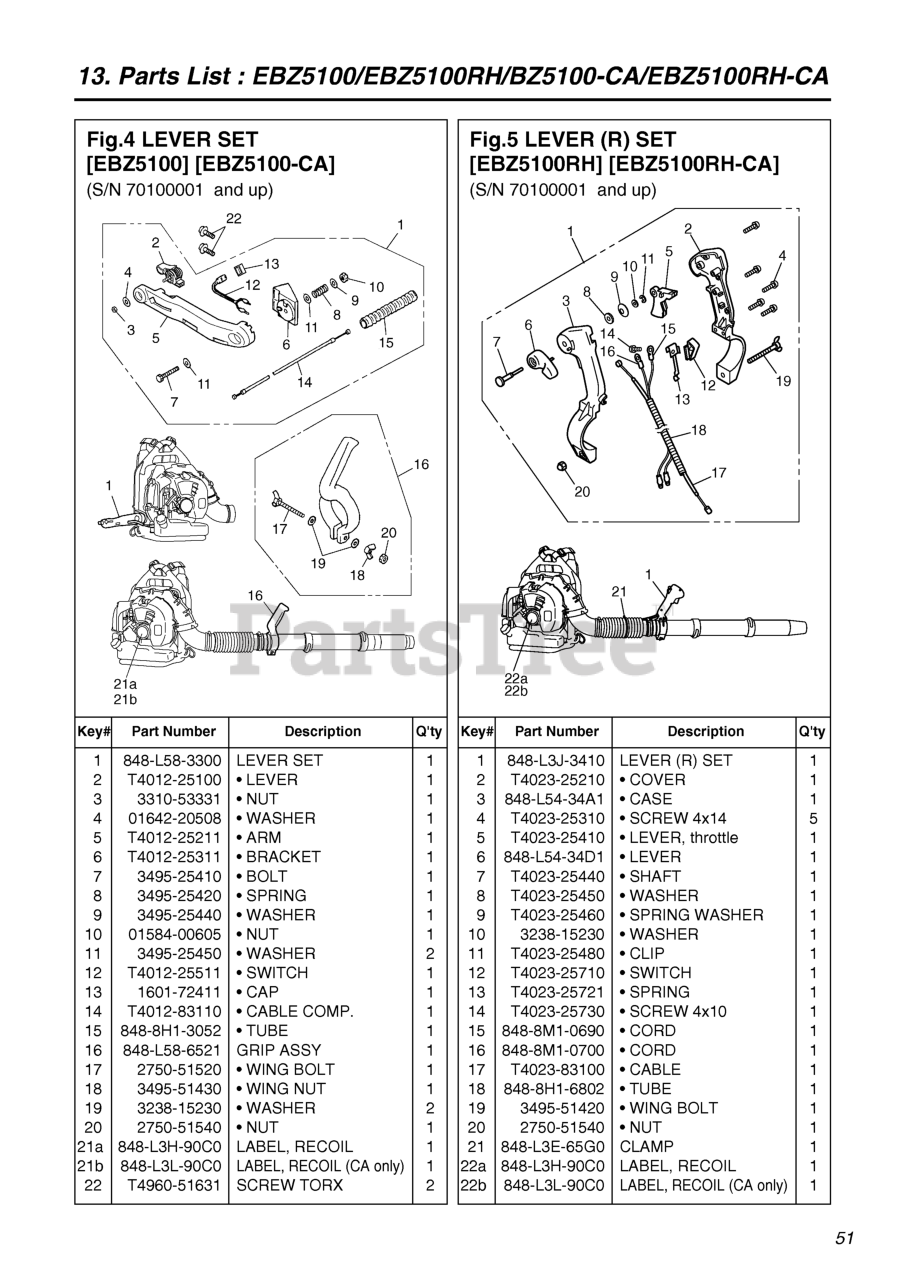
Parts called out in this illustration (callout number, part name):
1	LEVER SET (RPLS. T4012-25001)
2	LEVER
3	NUT (B)
4	WASHER, M5x.8(RPLS 01624-20508
5	ARM (RPLS T4012-25210)
6	BRACKET (RPLS -25310)
7	BOLT
8	SPRING
9	WASHER
10	NUT, M6 X 5
11	WASHER, FLAT
12	SWITCH (RPLS T4012-25510)
13	CAP SWITCH
14	CABLE COMPLETE
15	TUBE (REPLACES T4012-25610)
16	GRIP ASSY
17	WING BOLT
18	NUT, WING
19	WASHER
20	NUT
21A	LABEL, RECOIL
22	SCREW TORX
